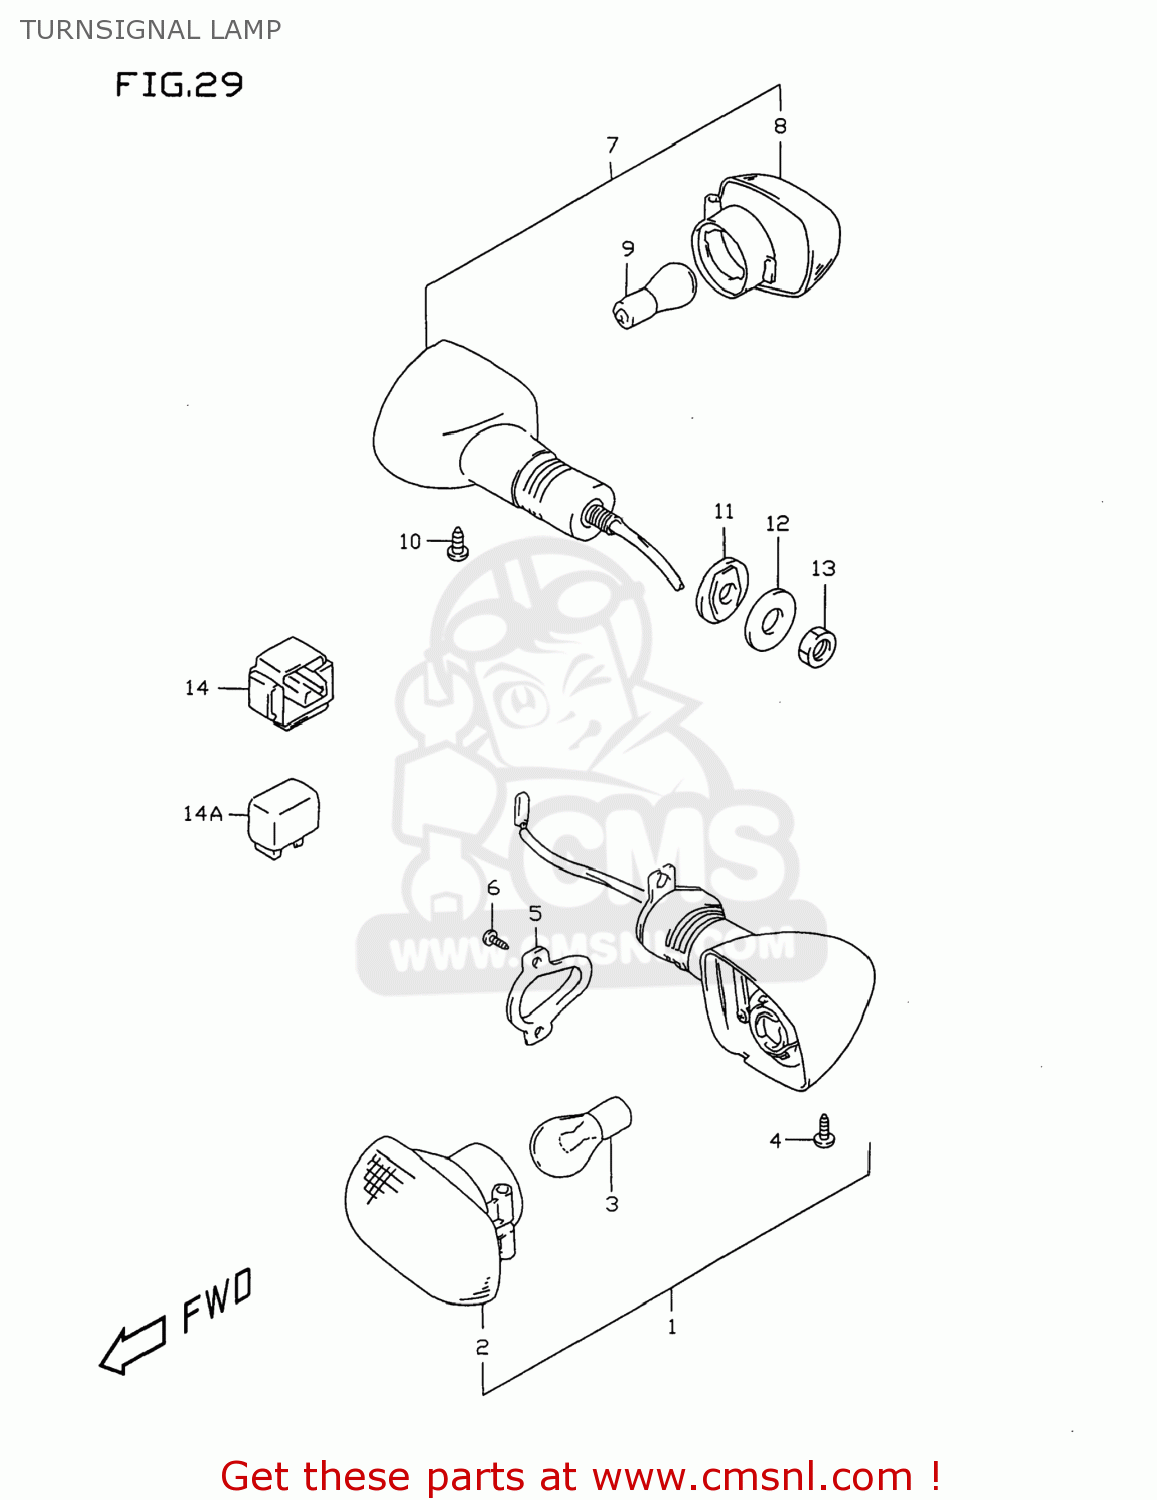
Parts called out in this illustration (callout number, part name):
1	LAMP ASSEMBLY,FRONT TURN SIGNAL
2	LAMP UNIT
3	BULB(12V21W)
4	SCREW
5	PLATE,FR TURNSIGNAL LAMP
6	SCREW
7	LAMP ASSY,RR TURNSIGNAL,R
8	LAMP UNIT
9	BULB(12V21W)
10	SCREW
11	SPACER,RR TURNSIGNAL
12	WASHER(10.5X30X2.3)
13	NUT
14	RELAY ASSY
14A	RELAY ASSY,TURNSIGNAL LAMP
